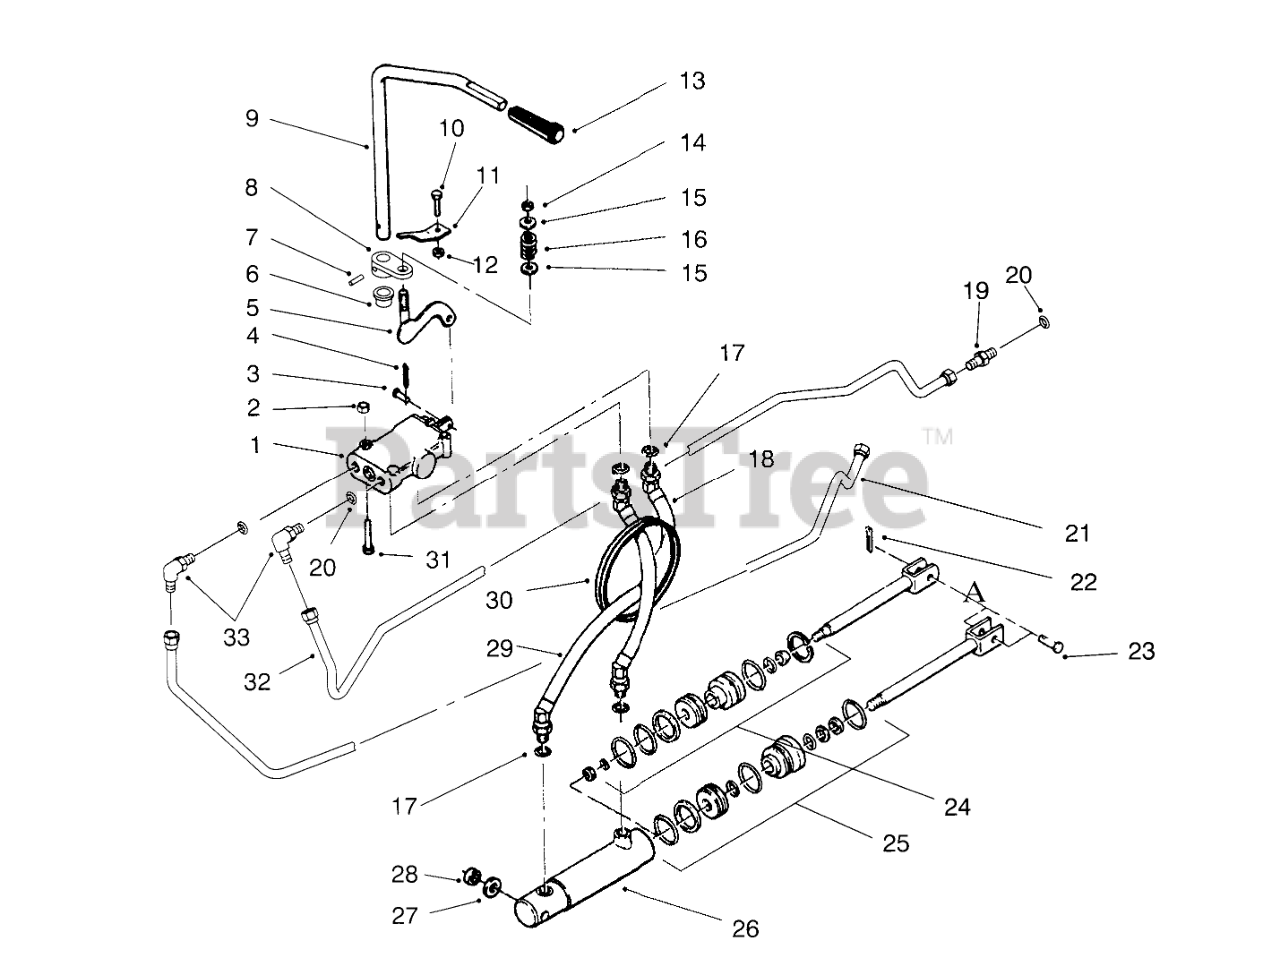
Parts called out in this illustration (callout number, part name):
1	Valve-Hydraulic (Incl. Ref. #3-4)
2	NUT-LOCK, NI
3	Pin
4	PIN-COTTER
5	WLDMT-LIFT BAR
6	NYLINER BUSHING
7	SPIROL PIN 7/32X7/8
8	ARM-CONTROL
9	ROD-LIFT CONTROL
10	SCREW-HH
11	BRACKET-CONTROL R B
12	NUT-LOCK, NI
13	KNOB-HYDRAULIC LIFT
14	NUT-LOCK, NI
15	WASHER-PLAIN
16	SPRING
17	O RING
18	Hose ASM-Hydraulic
19	Fitting-Straight Adapter (Incl. Ref. #20)
20	0-Ring
21	TUBE-HYD PRESSURE
22	PIN-COTTER
23	Pin-Clevis
24	S/A O-RING&GASKET AS
25	S/A 108872 HYD CYL
26	Cylinder-Hydraulic (Incl. Ref. #24-25)
27	Washer
28	SPACER-OUTER
29	Hose ASM-Hydraulic
30	GROMMET
31	SCREW-HH
32	TUBE-HYD RETURN
33	Fitting-90deg. (Incl. Ref. #20)
